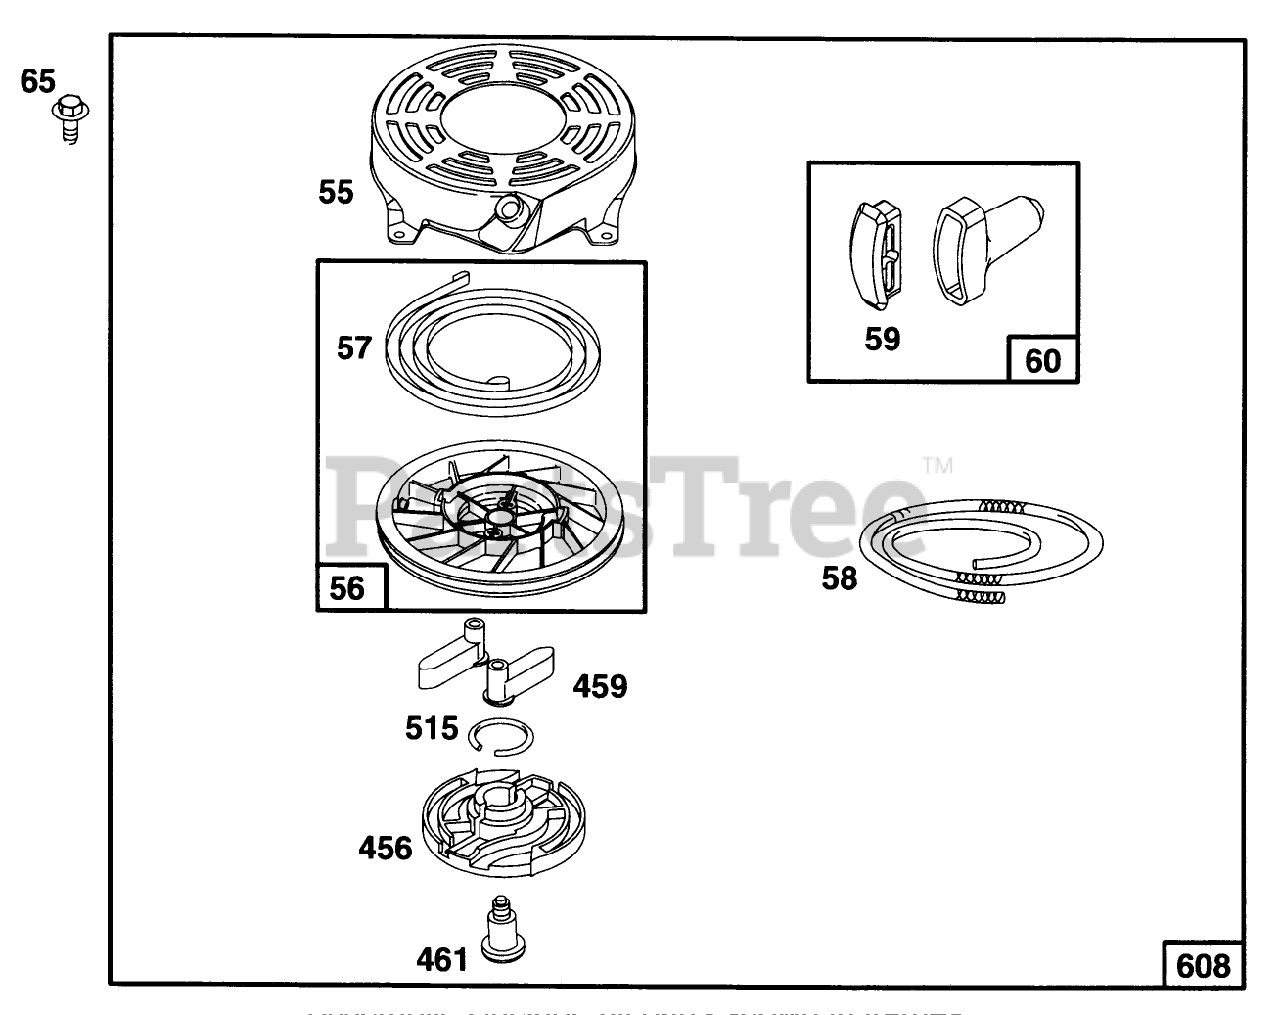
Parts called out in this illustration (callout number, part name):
56	PULLEY-STARTER, REWIND
59	INSERT-HANDLE, REWIND
456	RETAINER-STARTER, REWIND
459	PAWL-STARTER
515	SPRING-TORSION
